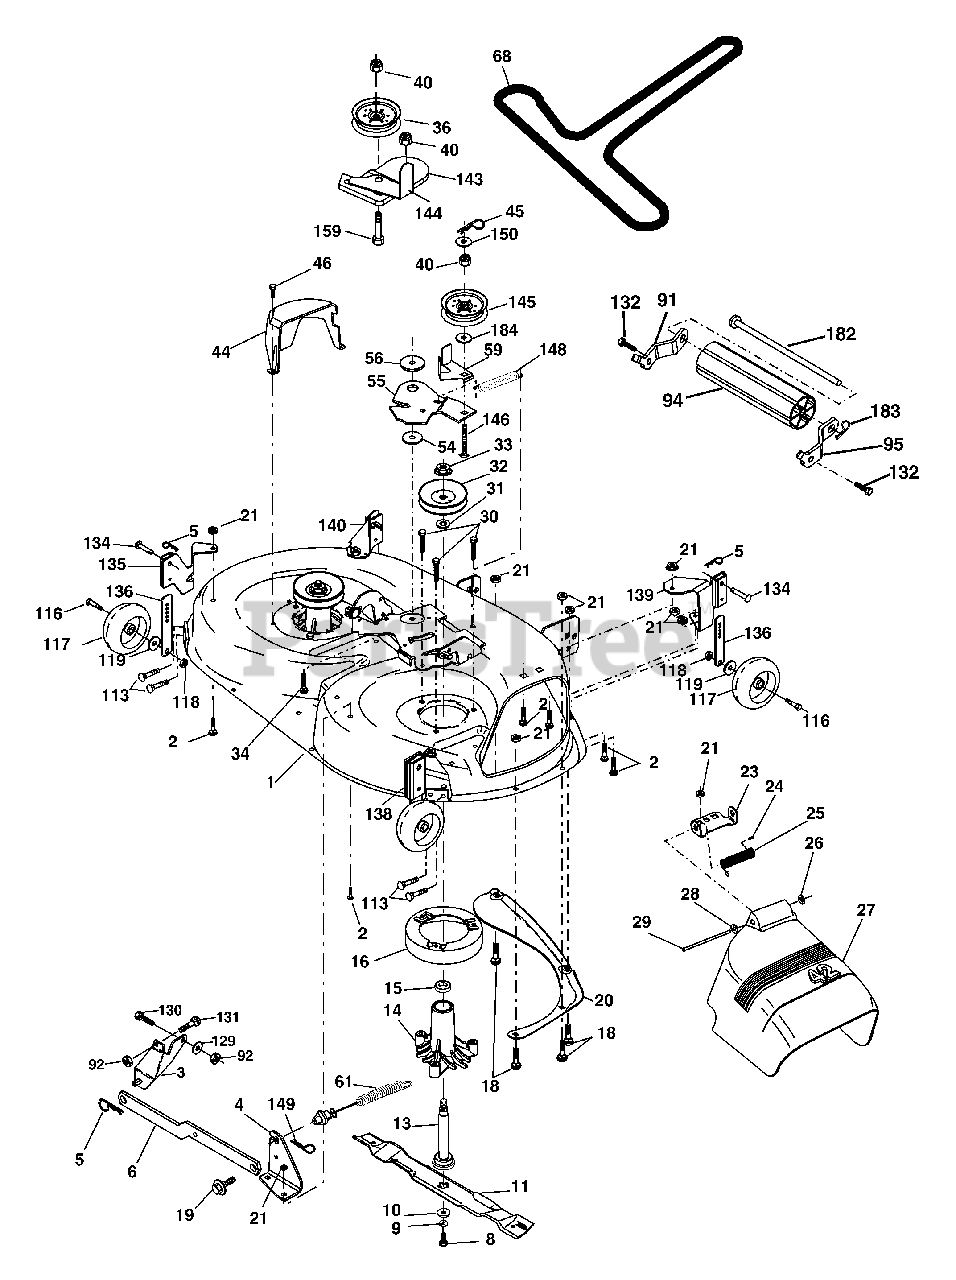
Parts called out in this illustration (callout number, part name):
1	Mower Deck Assembly, 42"
2	Bolt
3	Bracket Asm Fr. Sway Bar 3/42
4	Bracket Asm Deck 42" Sway Bar
5	Retainer Spring
6	Bar Sway Deck
8	Bolt 3/8-24 x 1.25 Gr. 8 patched
9	Washer, Lock
10	Washer, Hardened
11	Blade Mower 42" Hi-Lift
11	Blade, Mulching 42" Std
11	Blade Mulching 42" Premium
13	Shaft Assembly, Mandrel, Vented
14	Housing, Mandrel, Vented
15	Bearing, Ball, Mandrel
16	Stripper, Mandrel Deck
18	Bolt, Carriage 5/16-18 x 5/8
19	Bolt, Shoulder
20	Baffle, Vortex
21	Nut
23	Bracket, Deflector Mower 42"
24	Cap, Sleeve 80 x 112 Blk Mower
25	Spring, Torsion, Deflector 2 52
26	Nut, Push Phos & Oil
27	Shield, Deflector 42" Blk
28	Washer 11/32 x 5/8 x 16 Ga.
29	Rod, Hinge 42" 6 75 W/G
30	Screw Thdrol
31	Washer, Spacer Mower Vented
32	Pulley, Mandrel
33	Nut, Toplock
34	Bolt Carr SH 3/8-16 x 1-1/2 Gr.5
36	Pulley, Idler, Flat
40	Nut Lock 3/8-16
44	Guard, Mandrel, LH
45	Retainer
46	Screw, Thdrol 1/4-20 x 5/8 T
54	Washer, Hardened
55	Arm, Idler
56	Spacer, Retainer
59	Guard TUV Idler
61	Spring Ext Elect. Clutch
68	V-Belt, 42" Mower
91	Bracket Roller Nose RH
92	Nut Lock Hex w/Ins 3/8-16 unc
94	Roller Nose
95	Bracket Roller Nose RH
113	Screw 5/16-18
116	Bolt, Shoulder
117	Wheel, Gauge
118	Nut Centerlock 3/8-16
119	Washer 3/8 x 7/8 x 14 Ga.
129	Washer 13/32 x 13/16 x 12 Ga.
130	Bolt Fin HEx 3/8-16 unc x 1 Gr. 5
131	Bolt RDHD SQNK 3/8-16 unc x 1
132	Screw Hexwsh Thdrol
134	Pin Head Rivet
135	Bracket Asm. Whl Ga. R LH
136	Bar Adjusting Gauge Wheel
138	Bracket Asm Whl Ga. R RH
139	Bracket Asm. Whl Ga. F RH
140	Bracket Asm Whl Ga. F LH
143	Bracket Arm Idler 42"
144	Keeper Belt 42" Clutch Cable
145	Pulley Idler Flat
146	Bolt Carriage Idler
148	Spring Return Idler
149	Retainer Spring Yellow
150	Washer 9/32 x 3/4 x 10 Ga.
159	Bolt Rdhd Sqn 3/8-16 unc x 1-3/4
182	Rod Roller Nose
183	Retainer Spring
184	Washer 13/32 x 7/8 x 10 Ga.
